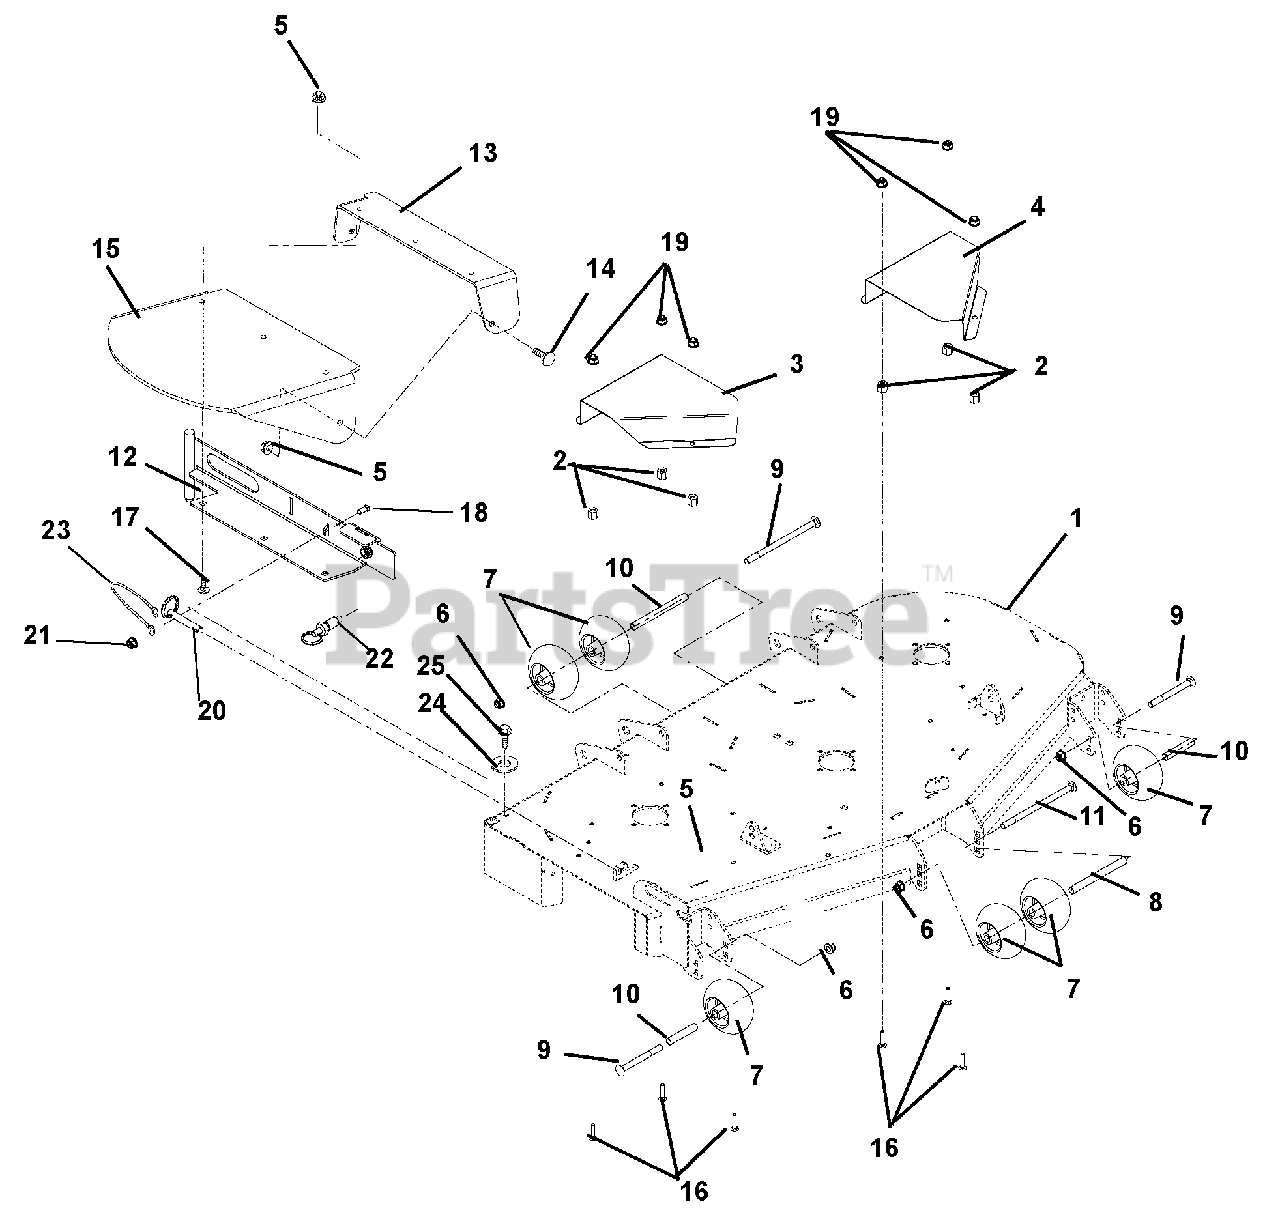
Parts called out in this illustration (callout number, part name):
1	WMT,60" SIDE DISCH DECK,10GA
1	WMT,52" SIDE DISCH,10GA,RED
1	WMT,48" SIDE DISCH,10GA,RED
2	NUT-HEAVY HEX .38-16 YWZC
3	60"-66" RH DECK BELT GUARD-RED
3	GUARD-44-52 RH SPINDLE SHEAVE
4	GUARD, 60" LH DECK BELT - RED
4	44"-52"LH DECK BELT GUARD -RED
5	@NUT-LK-NYL-FLG .38-16 YWZC
6	@NUT-LK-NYL-FLG .50-13 YWZC
7	ANTI-SCALP WHEEL - 5X3 CTR
8	SPACER, .510X.625X6.50
8	SPACER, .510X.625X3.35
9	BLT-RDHDSQNK .50-13X5.00 GR5YZ
10	SPACER, .510X.625X3.35
11	@BLT-RDHDSQNK .50-13X8.50 G5YZ
12	52"-60" DISCH CHUTE MTG WMT-RD
12	44"-48" DISCH CHUTE MTG WMT-RD
13	RUBBER DISCH CHUTE SUPPORT-RED
14	@BLT-RDHDSQNK .38-16X1.00 G5YZ
15	CHUTE, RUBBER DISCHARGE
16	@BLT-HEX .38-16X1.25 GR5 YWZC
17	@BLT-RDHDSQNK .38-16X1.25 G5YZ
18	@BLT-HEX .25-20X.75 GR5 YWZC
19	@NUT-SPNLK-FLG .375-16 YWZC
20	PIN, SPRING BALL .375OD X 1.50
21	@NUT-LK-TOP-FLG .25-20 YWZC
22	Pull Pin
23	CABLE, 6.0 LANYARD, NYLON
24	BUMPER,RECESSED1.50X.63 W/.31
25	@SCR-TAP .31-18X.75 HWH TR YWZ
